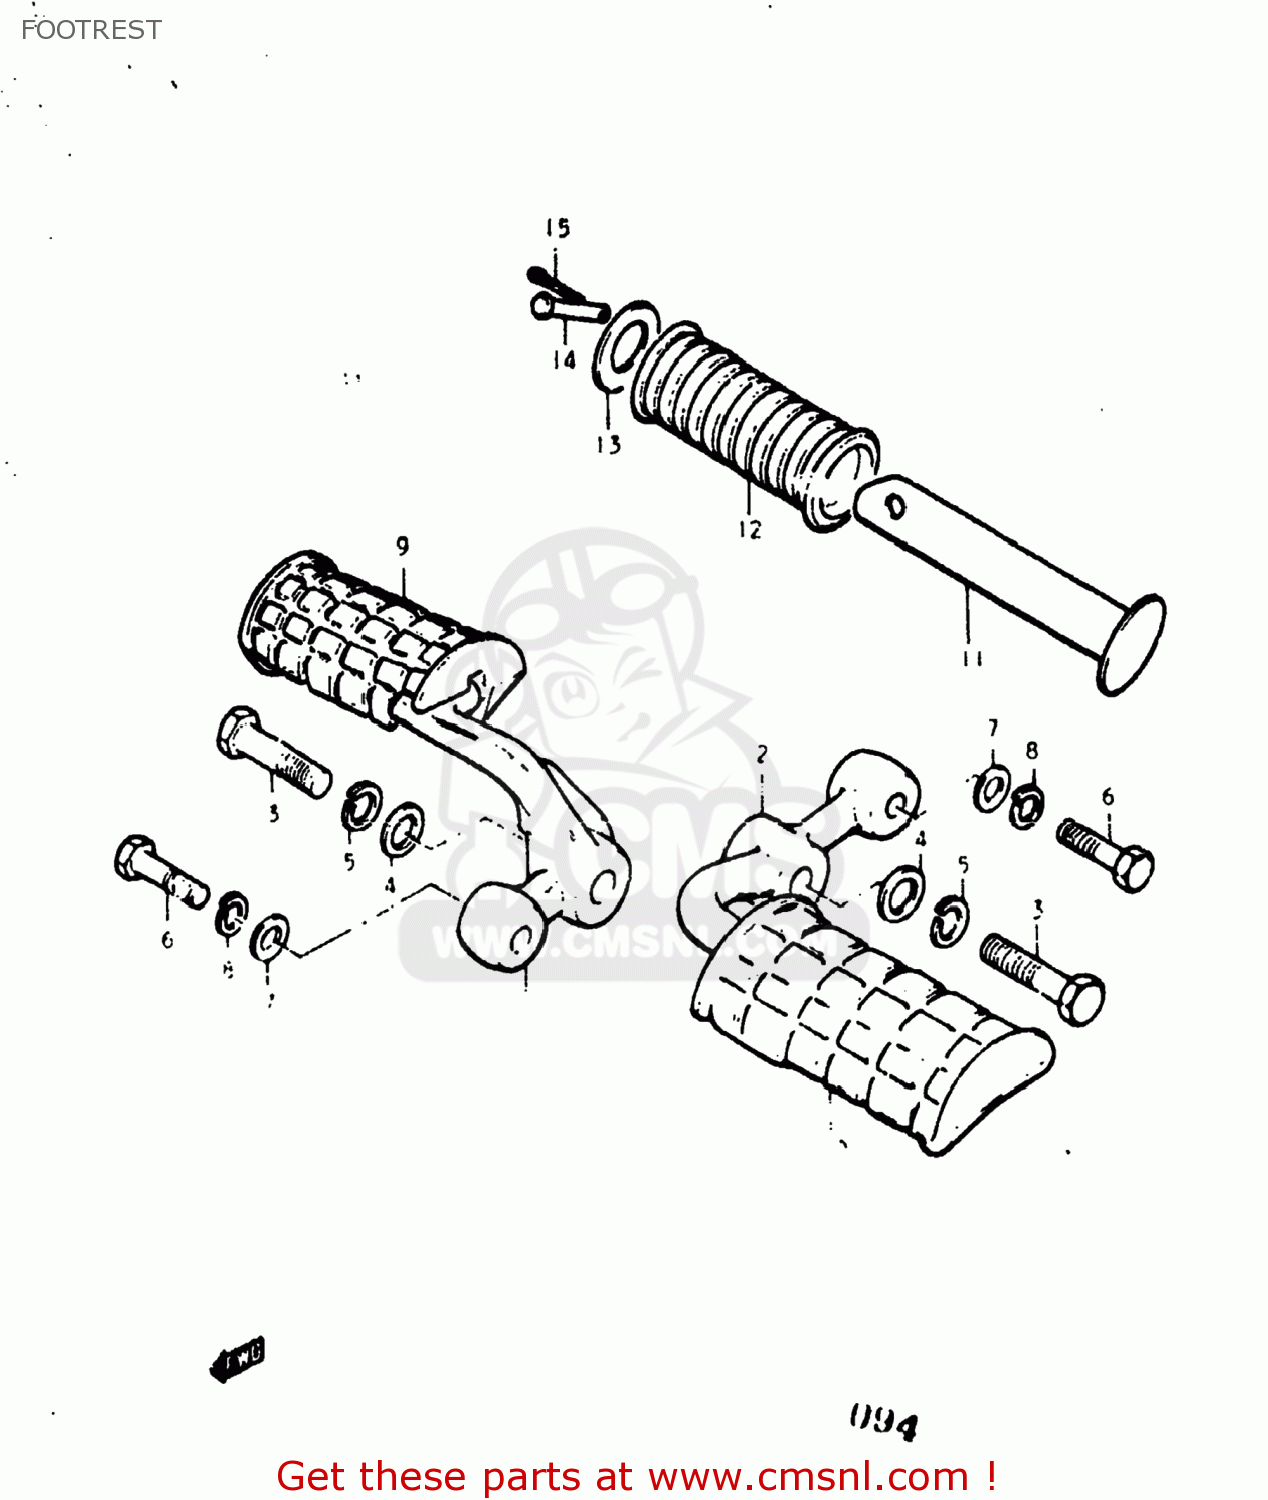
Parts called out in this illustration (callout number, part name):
1	BAR,FRONT FOOTREST
2	BAR,FRONT FOOTREST,LEFT
3	BOLT
4	WASHER
5	LOCK WASHER
6	BOLT 8X40
7	WASHER
8	LOCK WASHER
9	RUBBER,FR FOOTREST,R
10	RUBBER,FOOTREST
11	BAR,FOOTREST RUBBER
12	RUBBER,PILLION FOOTREST
13	WASHER (19.5X32X2)
14	PIN
15	PIN 20X20
